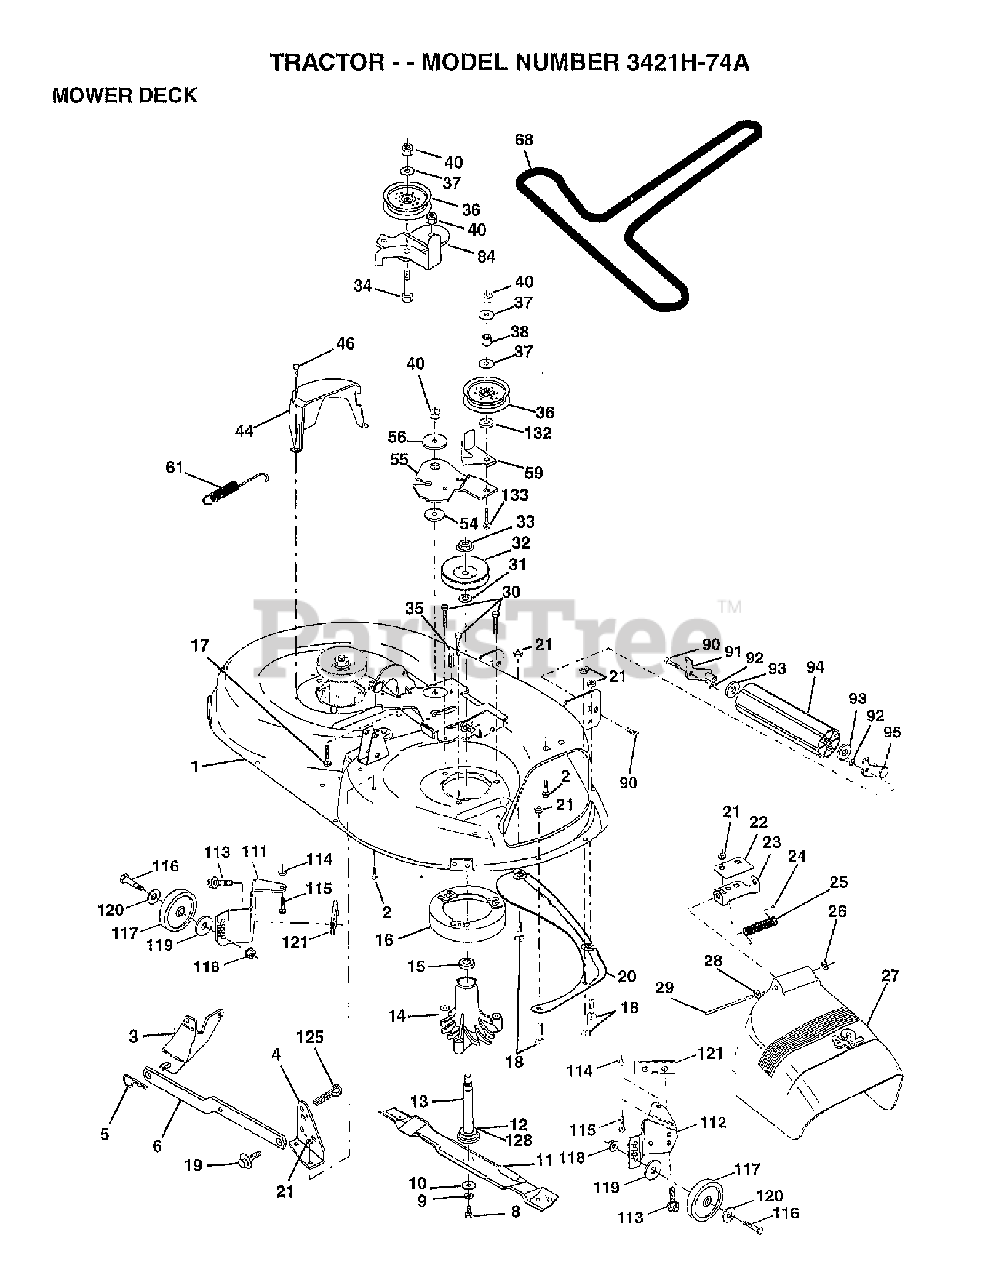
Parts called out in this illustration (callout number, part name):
2	BOLT
3	BRKT ASM SWAY BAR
4	BRKT DECK SW BAR
5	RETAINER SPRING
8	BLADE BOLT
10	WASHER.BLADE
11	BLADE 42" LOW-LIFT VENT DECK
12	BEARING.BALL.#6204.(MANDREL)
13	SHAFT ASM VENT
14	HSG MANDREL
17	BOLT CARRIAGE
18	BOLT
19	BOLT SHD 5/16-18
21	LOCKNUT
23	DEFLECTOR BRACKET
24	CAP-SLEEVE LT
25	DEFLECTOR SPRG T
26	NUT PUSH M
27	SHIELD.DEFLECTOR.MOWER.42".BLK
28	WASHER
29	ROD.HINGE
30	Hex Washer Head Bolt, .313-18 X 1.19
31	WASHER
32	PULLEY/MANDREL
34	BOLT
35	FASTENER.XMAS.TREE
36	IDLER-FLAT GT
38	IDLER SPRING SPACER
40	LOCKNUT
44	MANDREL GUARD LH
46	SCREW.1/4-20X5/8
59	GUARD, BELT
61	SPRING EXTENSION
68	BELT V SECONDARY
90	BOLT
91	Roller Bracket Assembly, LH
92	NUT
94	MANUAL, OPERATOR
113	Screw, Lt
116	BOLT
117	GUAGE WHEEL GT
118	LOCKNUT
119	WASHER
121	BRACKET.EXTRUDED.GAGE.WHEEL
128	WASHER FELT
132	WASHER GT
